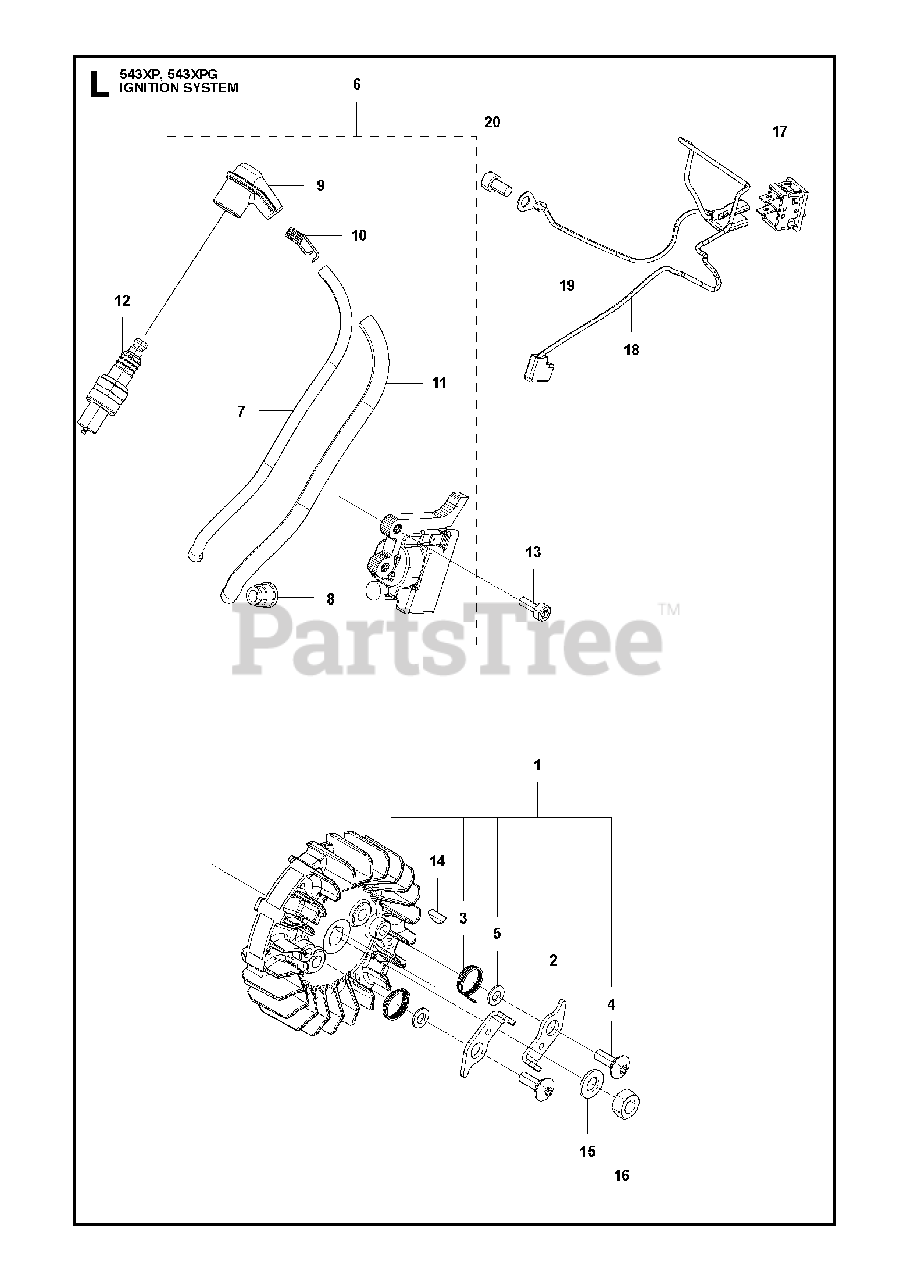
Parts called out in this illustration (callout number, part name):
1	FLYWHEEL ASSY
2	PAWL
3	SPRING
4	SCREW T27 XC23
5	WASHER 5X10X10
6	IGNITION MODULE ASSY
7	CODE XC23
8	CAP
9	CAP
10	SPRING
11	TUBE XC23
12	PLUG CMR7H
13	BOLT
16	NUT Z335043231
17	SWITCH A
20	BOLT
